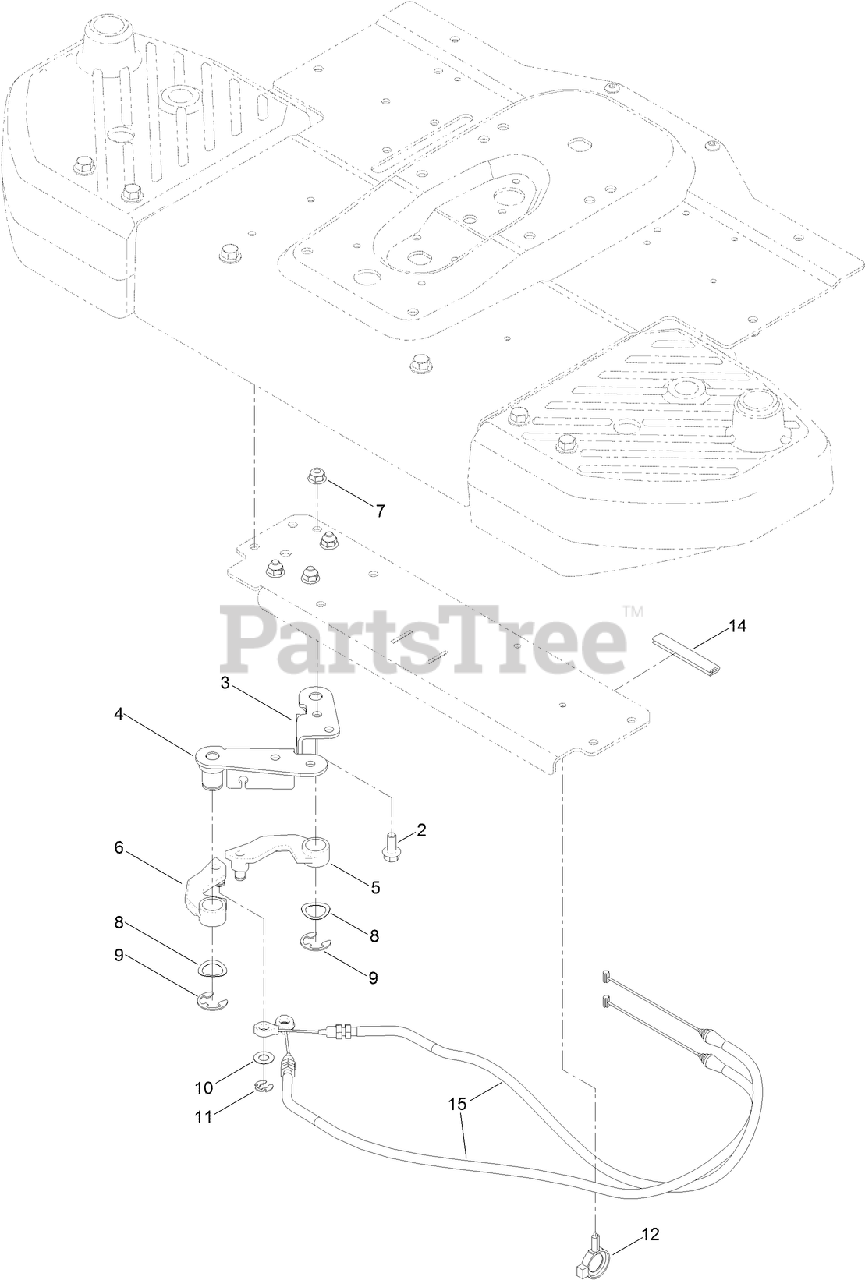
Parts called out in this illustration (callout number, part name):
2	SCREW-HHF
3	CABLE BRACKET ASM
4	CABLE BRACKET ASM
5	ARM-CABLE, RH
6	ARM-CABLE, LH
7	NUT-HF, NI
8	WASHER-BOWED
9	E-RING
10	WASHER-THRUST
11	RING-RETAINING
12	CLAMP-HOSE
14	STRIP-SEAL
15	CABLE-STEERING
